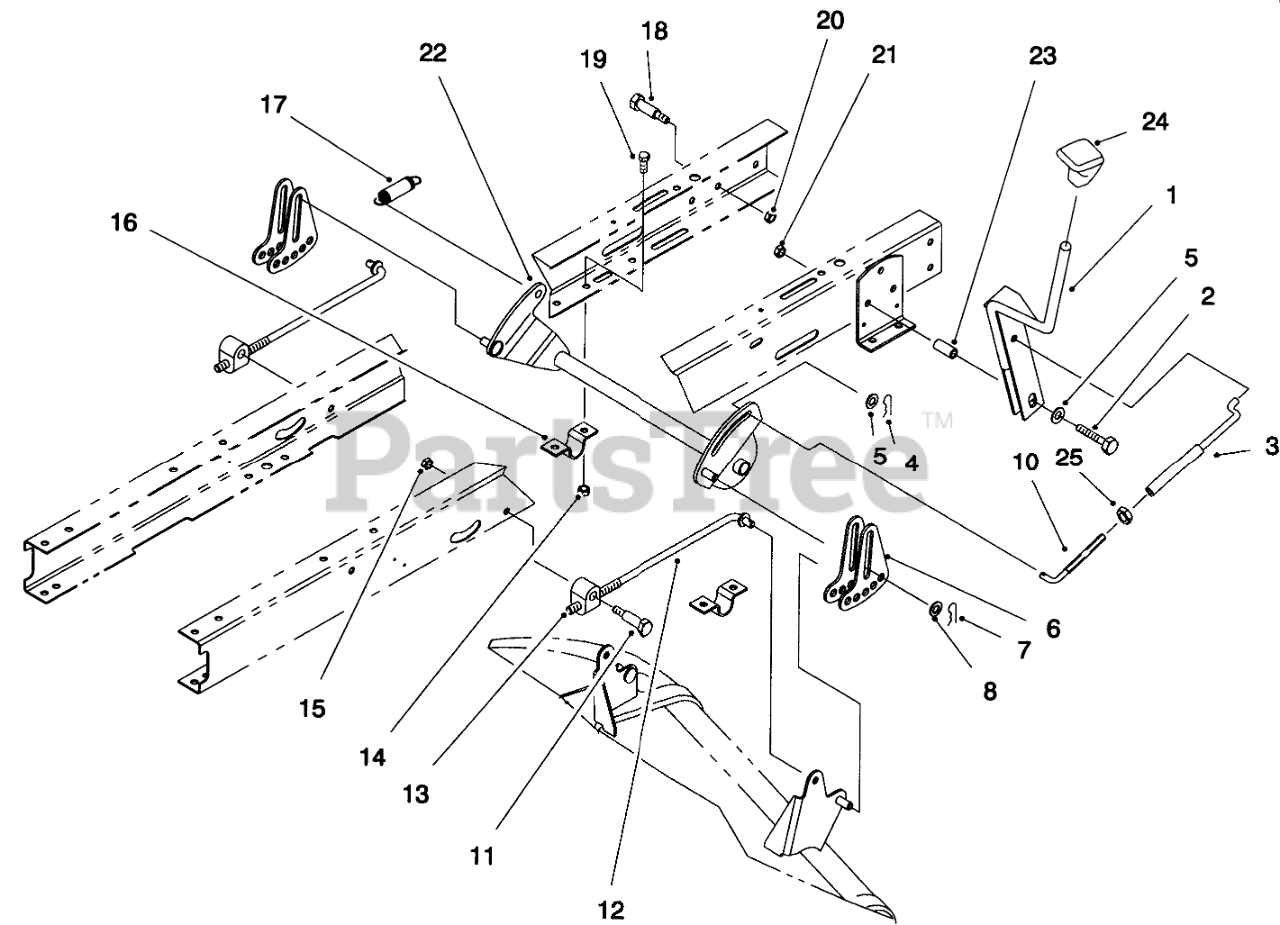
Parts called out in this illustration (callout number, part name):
1	Lever-H.O.C.
2	SCREW-HH
4	PIN-COTTER
5	WASHER-FLAT
6	Link-Adjusting H.O.C
7	PIN-COTTER
8	WASHER-HARDENED
10	LINK-HOC
11	SCREW-SHOULDER, HH
12	ROD-HANGER, REAR
13	TRUNNION-HOC
14	NUT-LOCK, NI
15	NUT-LOCK, NI
16	CLAMP-PIVOT, HOC
17	SPRING-EXTENSION
18	SCREW-SHOULDER, HH
19	SCREW-HH
20	NUT-LOCK, NI
21	NUT-LOCK, NI
22	Pivot-H.O.C.
23	SPACER
24	SHIFT KNOB
25	NUT-JAM
